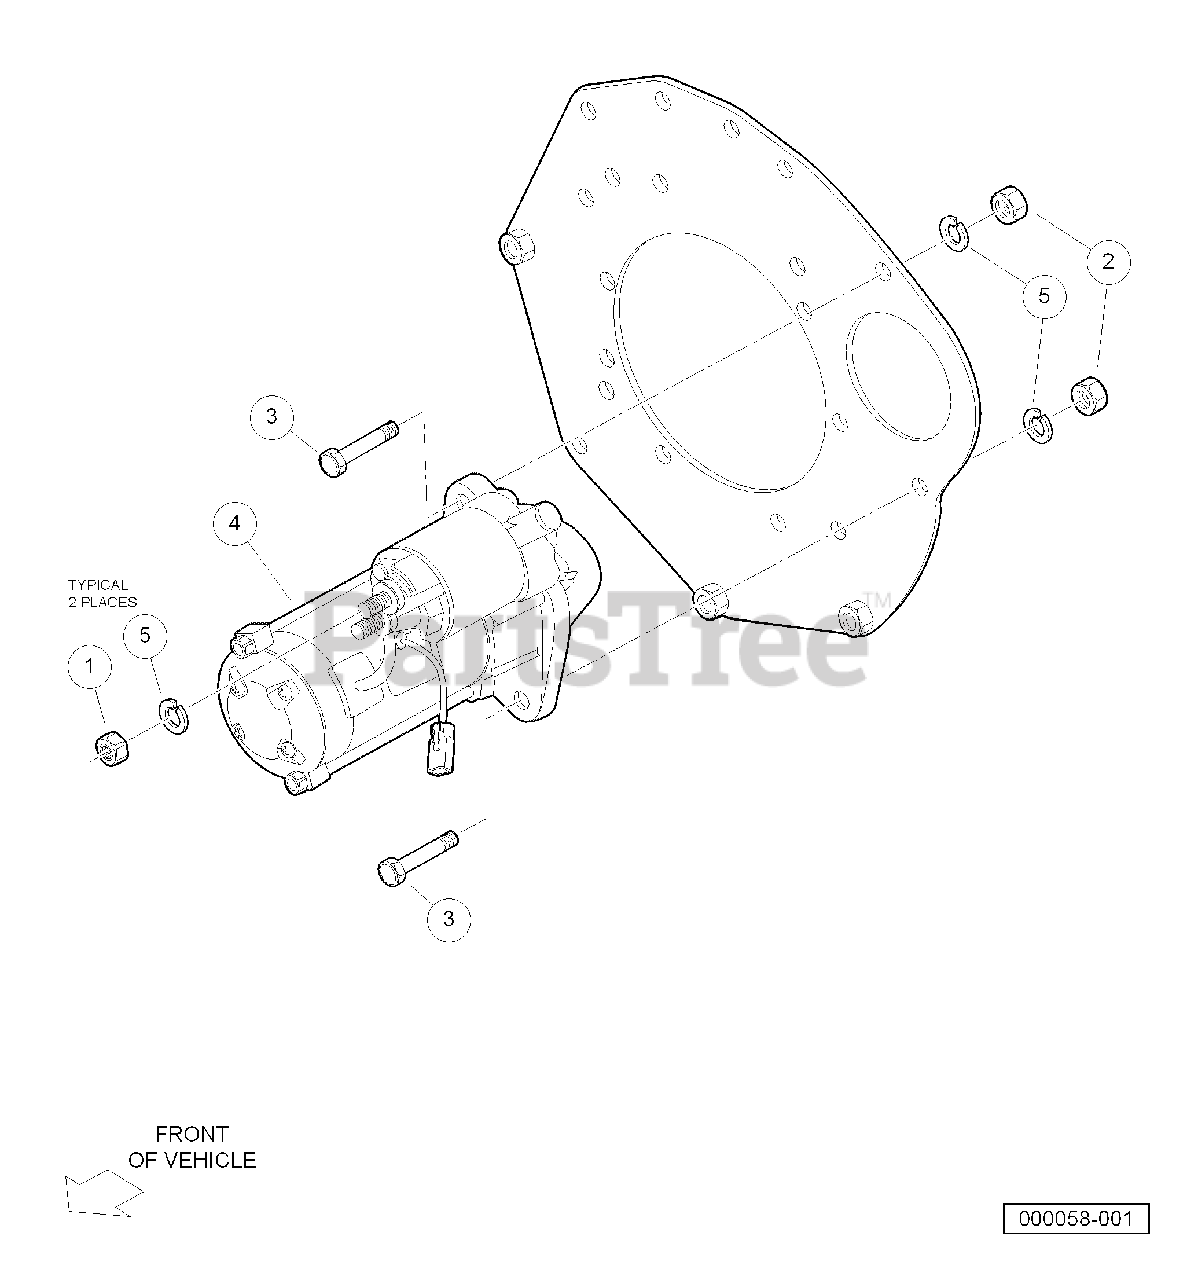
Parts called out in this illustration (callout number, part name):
1	Nut, D722, Starter
2	Nut, M8, Plate
3	Bolt, M8 X 1.25 X 28
4	Motor, Starter
5	Washer, Spring, D722, Starter
